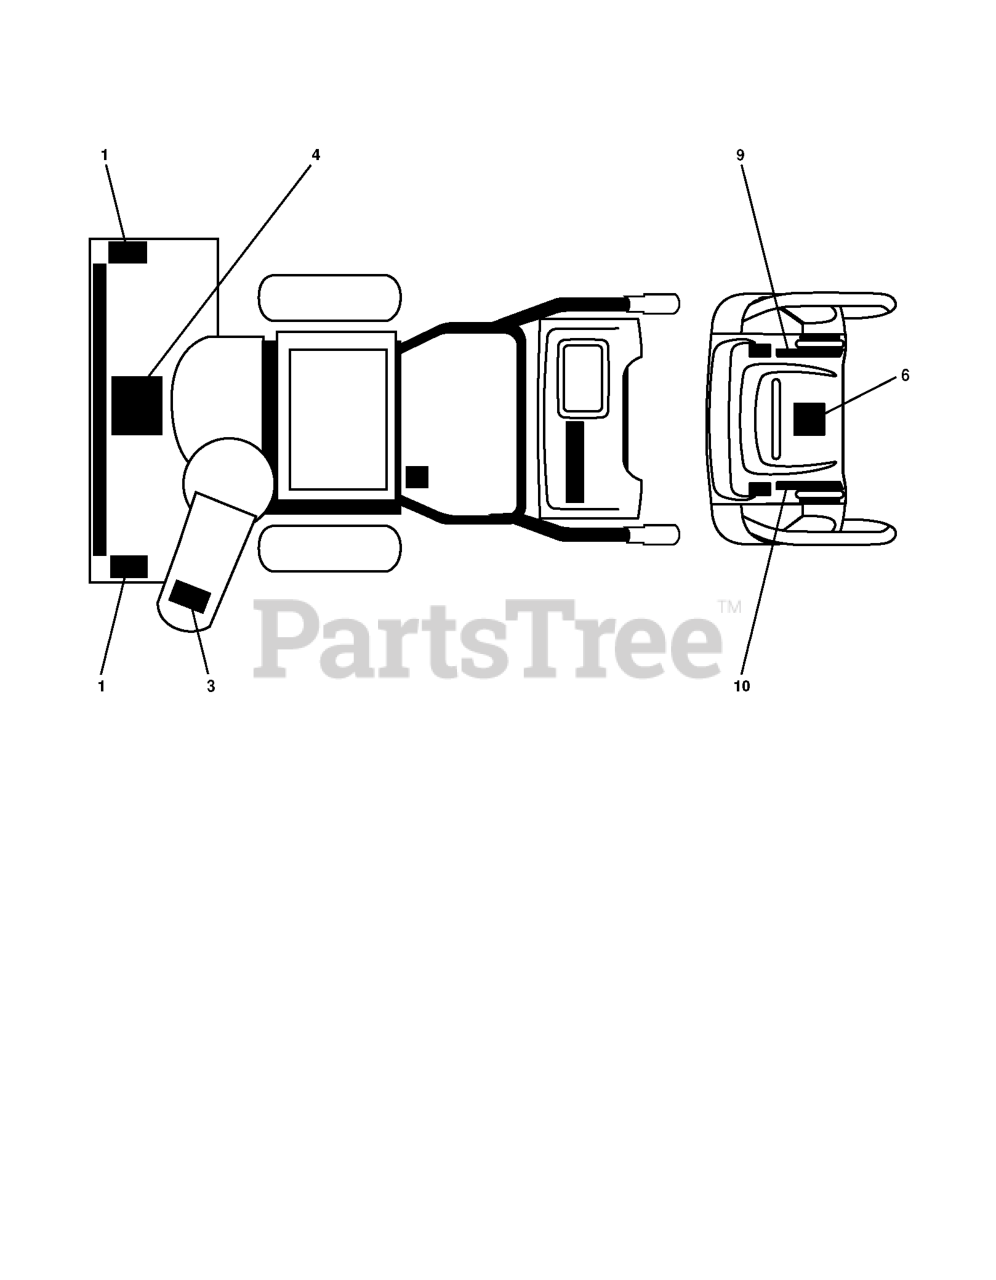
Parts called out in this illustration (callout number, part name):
1	DECAL.SNOWTHR.AUGER
3	DECAL.SNOWTHR.CHUTE.SAFETY
4	DECAL.SNOWTR.READ.OWN.MAN.E/F
6	DECAL, INSTRUCTION
9	DECAL SPEED CONTROL
10	DECAL, REMOTE DEFLECTOR
